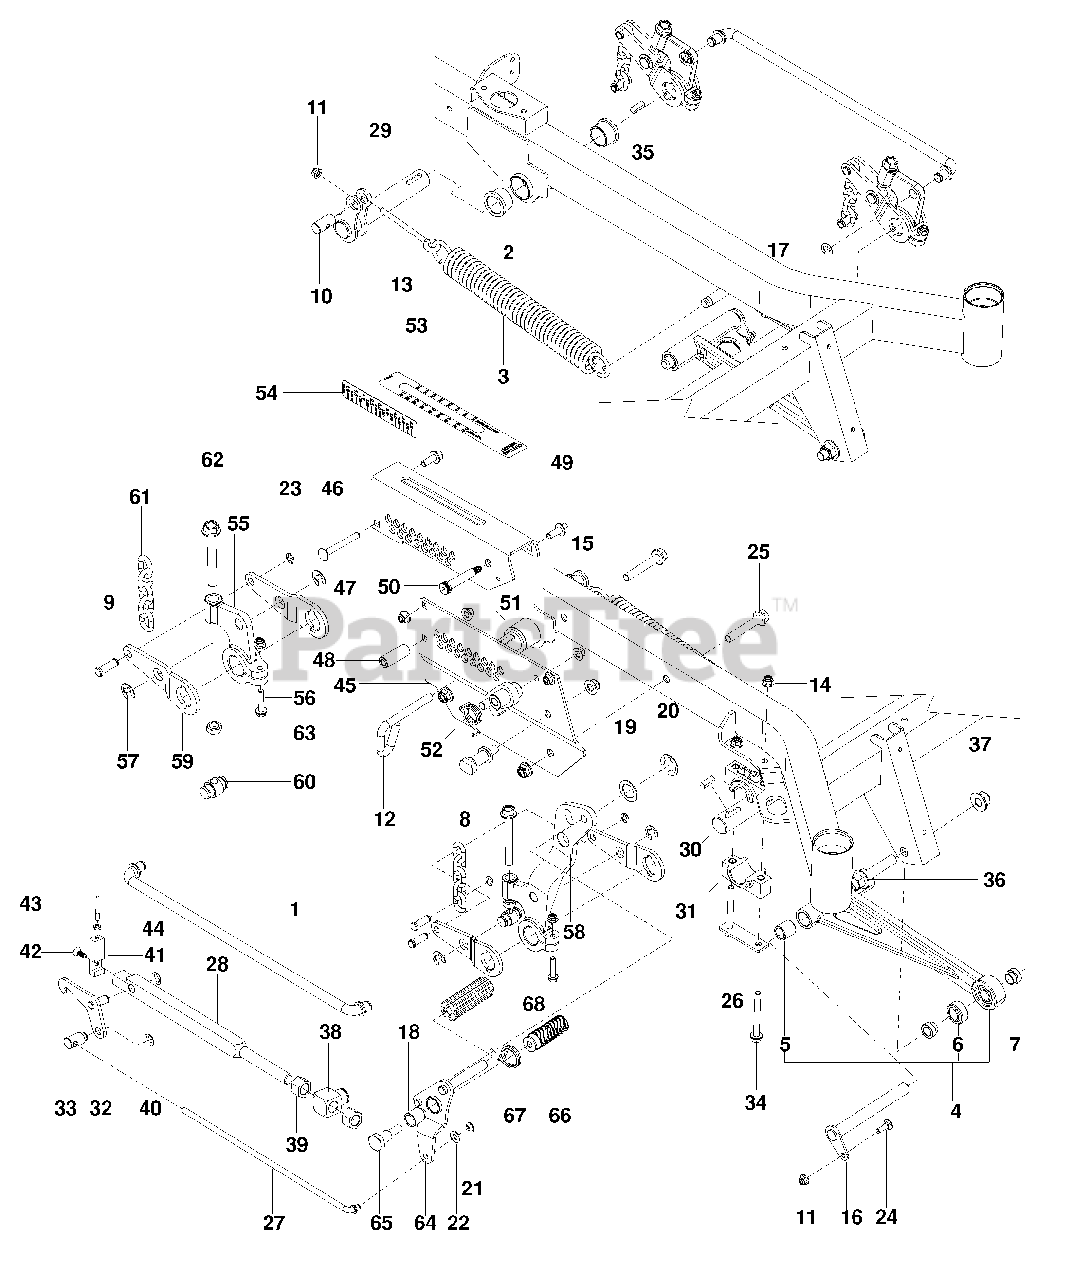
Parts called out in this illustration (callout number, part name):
2	Bolt 7/16-20 X 1 1/2 Hex Nyl
3	Spring, Extension
4	Strut Assy
5	Bushing, Sleeve 3/4 X 1
6	Balljoint 3/4 Swivel
7	Spacer, Strut
8	Guide, Height Bar
9	Pin, 7/16 Clevis
10	Pivot, Spring
11	Nut 5/16-18 Hex Flg Nyloc
12	Pin, Height
13	Eyebolt 4 1/2
14	Nut 3/8-16 Hex Flg Nyloc
15	Nut 1/2-13 Hex Flg Nyloc
16	Pin, Strut
17	E-Ring 5/8
18	Bushing, Sleeve 3/4 X 1
19	Bushing 1" X 14 Ga
20	E-Ring 1"
21	E- Ring 3/8"
22	Washer, 3/8 Sae Flt
23	E-Ring 7/16"
24	Bolt 5/16-18 X 1 Rd Hd
25	Bolt 1/2-13 X 3 Hex Flg
26	Plate, Pillow Block
27	Rod, Height Latch
28	Bar, Height
29	Shaft, Rr Lift
30	Shaft, Lift, Ft
31	Block, Pillow
32	Latch, Height
33	Swivel, Height Latch
34	Screw 3/8-16 X 3 1/2 Hex Flg
35	Key 5/16 Sq X 1
36	Screw 5/8-11 X 3 Hex Flg
37	Nut 5/8-11 Flg Nyloc
38	Swivel, Height Bar
39	Nut 3/4-10 Hex
40	E-Ring 1/2"
41	Cap, Height Bar
42	Screw 5/16-18 X 3/4 Hex Sckt
43	Link, Indicator
44	Nut 1/4-20 Jam
45	Plate, Inner Height
46	Plate, Outer Height
47	Bolt 3/8-16 X 3 Rd Hd Gr2
48	Spacer, Height Plate
49	Screw 3/8-16 X 1 Hex Flg
50	Bolt 1/2 X 2 1/4, 3/8-16 Shldr
51	Latch, Transport
52	Spring, Torsion
53	Decal, Height
54	Decal, Height
55	Arm, Cast Lift
56	Screw 5/16-18 X 1 1/2 Hex Flg
57	E-Ring 3/4"
58	Lever, Deck Lift
60	Shaft, Lift Trunion
61	Lift Chain
62	Bolt 1/2-13 X 4 Hex Tpblt
63	Nut 1/2-13 Hex Jam
64	Pedal, Release
65	Bolt, Shoulder
66	Pad, Foot Pedal
67	Spring, Torsion
68	Pedal, Deck Height
